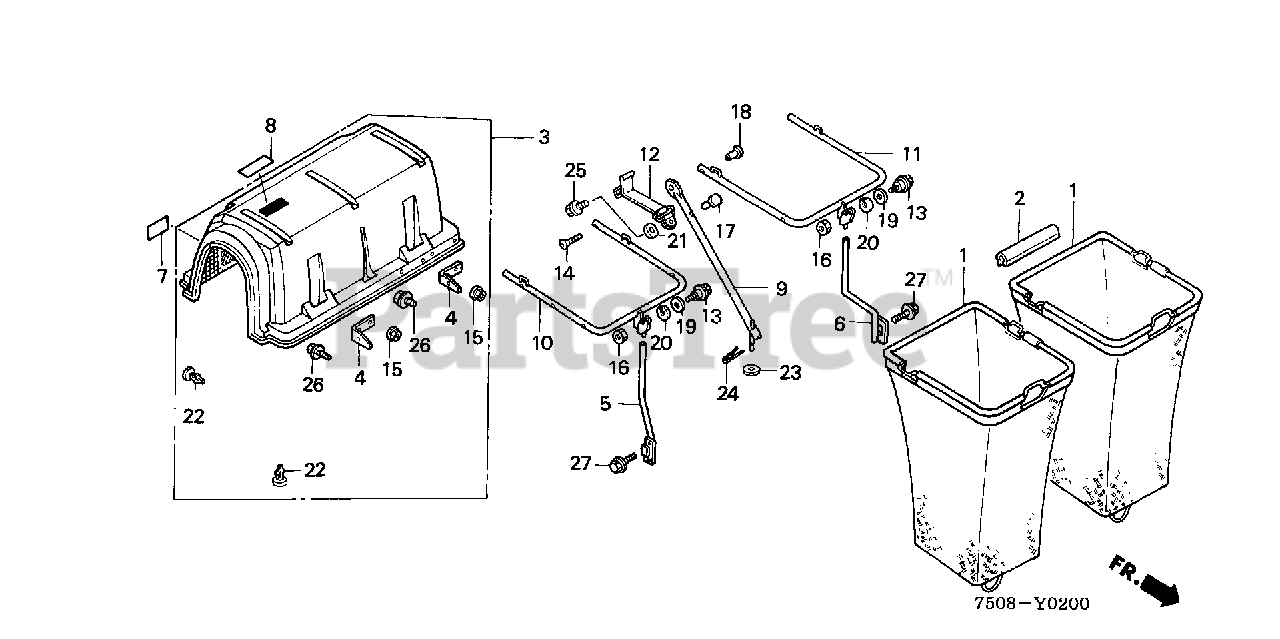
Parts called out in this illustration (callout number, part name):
1	BAG ASSY., GRASS
1	BAG ASSY., GRASS (ENGLISH)
1	BAG, GRASS
2	CLIP, GRASS BAG TUBE
3	HOPPER ASSY., TOP
4	HINGE, HOPPER TOP
5	POST, R. SUPPORT
6	POST, L. SUPPORT
7	LABEL, HOPPER TOP (E)
7	LABEL, HOPPER TOP
8	LABEL, HOPPER TOP ROOF (E)
8	LABEL, HOPPER TOP ROOF
9	BRACE, SUPPORT
10	STAY, R. SUPPORT
11	STAY, L. SUPPORT
12	BAND ASSY., HOPPER TOP
13	BOLT, HINGE (10MM)
14	SCREW, FLAT (8X45)
15	NUT, FLANGE (6MM)
16	NUT, AXLE (10MM)
17	NUT, PIPE (6MM)
18	NUT, PIPE (8MM)
19	WASHER, THRUST (14MM)
20	WASHER, SPRING (14MM)
21	WASHER (3/8")
22	CLIP, SCREEN
23	WASHER, FLAT (10MM)
24	PIN, LOCK (10MM)
25	BOLT, FLANGE (6X16)
26	BOLT, FLANGE (6X18)
27	BOLT, FLANGE (8X20)
